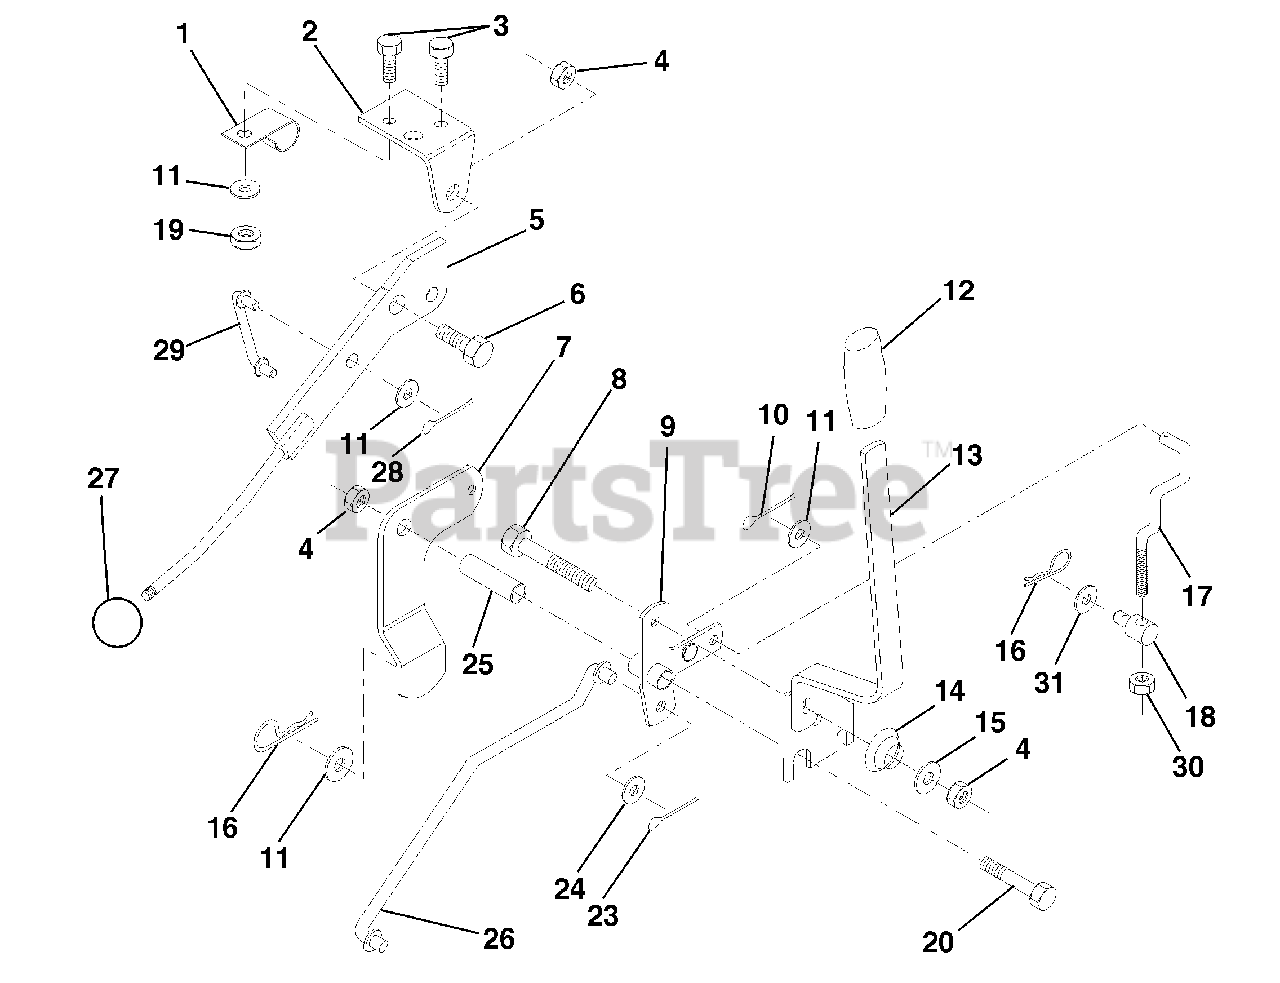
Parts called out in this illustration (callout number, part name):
1	Clip, Insulated
2	Bracket, Mower Clutch
3	Bolt, Fin. Hex 1/4-20 UNC x 1/2 Gr. 5
4	Nut, Crownlock 3/8-16 UNC
5	Assembly, Clutch Lever
6	Bolt, Shoulder
7	Assembly, Mower Clutch Arm
8	Bolt, Hex 3/8-16 UNC x 2-1/4
9	Assembly, Bellcrank Lift
10	Pin, Cotter 1/8 x 3/4
11	Washer 13/32 x 13/16 x 16 Ga.
12	Grip, Handle
13	Assembly, Lift Handle
14	Spring, Compression
15	Washer 13/32 x 3/4 x 12 Ga.
16	Retainer, Spring
17	Link, Front Lift
18	Trunnion, Threaded 3/8-16
19	Nut, Crownlock 1/4-20
20	Bolt, Fin. Hex 3/8-16 UNC x 2-3/4
23	Pin, Cotter 1/8 x 1
24	Washer 17/32 x 1 x 12 Ga.
25	Tube, Spacer
26	Rod, Mower Lift
28	Pin, Cotter 3/32 x 3/4
29	Link, Mower Clutch
30	Nut Hex Jam 3/8-16 x 1.30
31	Washer 13/32 x 1-1/4 x 12 Ga.
